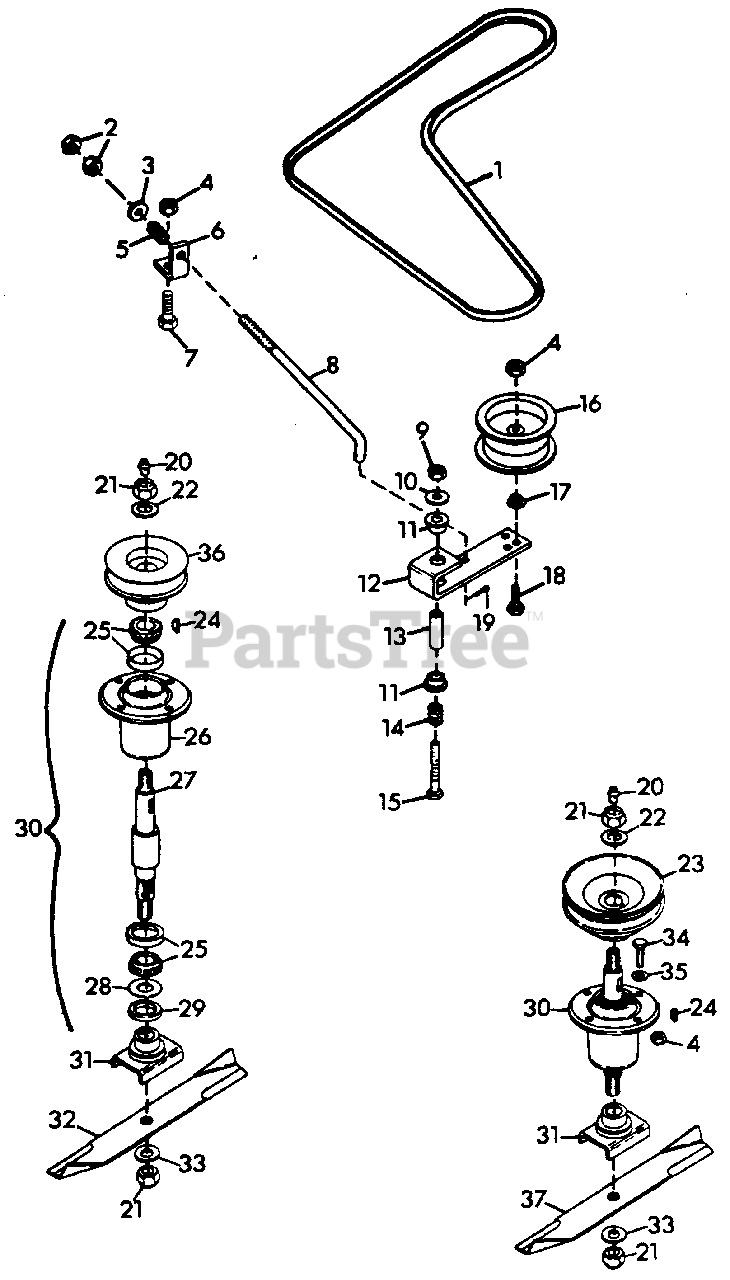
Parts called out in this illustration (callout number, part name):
1	Belt, Pro-32 Mower
2	Nut, Hex 3/8-24
3	Washer, Flat .406x.812x.065
4	Nut, Lock 3/8-16
5	Spring, Compression 1x.78x338
6	Bracket, Belt Tensioner
7	Bolt, Hex 3/8-16x.875
8	Rod, Idler
9	Nut, Lock 1/2-13
10	Washer, Flat .531x1.250x.100
11	Bushing, Nylon .76x1.00x.600 Flg.
12	Arm, Idler Pivot
13	Spacer
14	Spring, Compression 1x.80x36
15	Bolt, Hex 1/2-13x3.25
16	Pulley, Idler
17	Bushing
18	Bolt, Hex 3/8-16x2.25
19	Pin, Cotter .09x.75
20	Fitting, Lube 1/8
21	Nut, Lock 5/8-11
22	Washer, Flat .687x1.312x.122
23	Sheave, Spindle
24	Key, Woodruff 1/4x1 Hard #15
25	Assembly, Bearing
26	Housing, Bearing
27	Shaft, Spindle
28	Washer, Flat .975x1.970x.030
29	Seal, Steel
30	Assembly, Spindle
31	Weldment, Blade Cradle
32	Blade
33	Washer, Flat .656x1.312x.095
34	Bolt, Hex 3/8-16x1.25
35	Washer, Flat .438x1.00x.083
36	Sheave, Spindle
37	Blade
